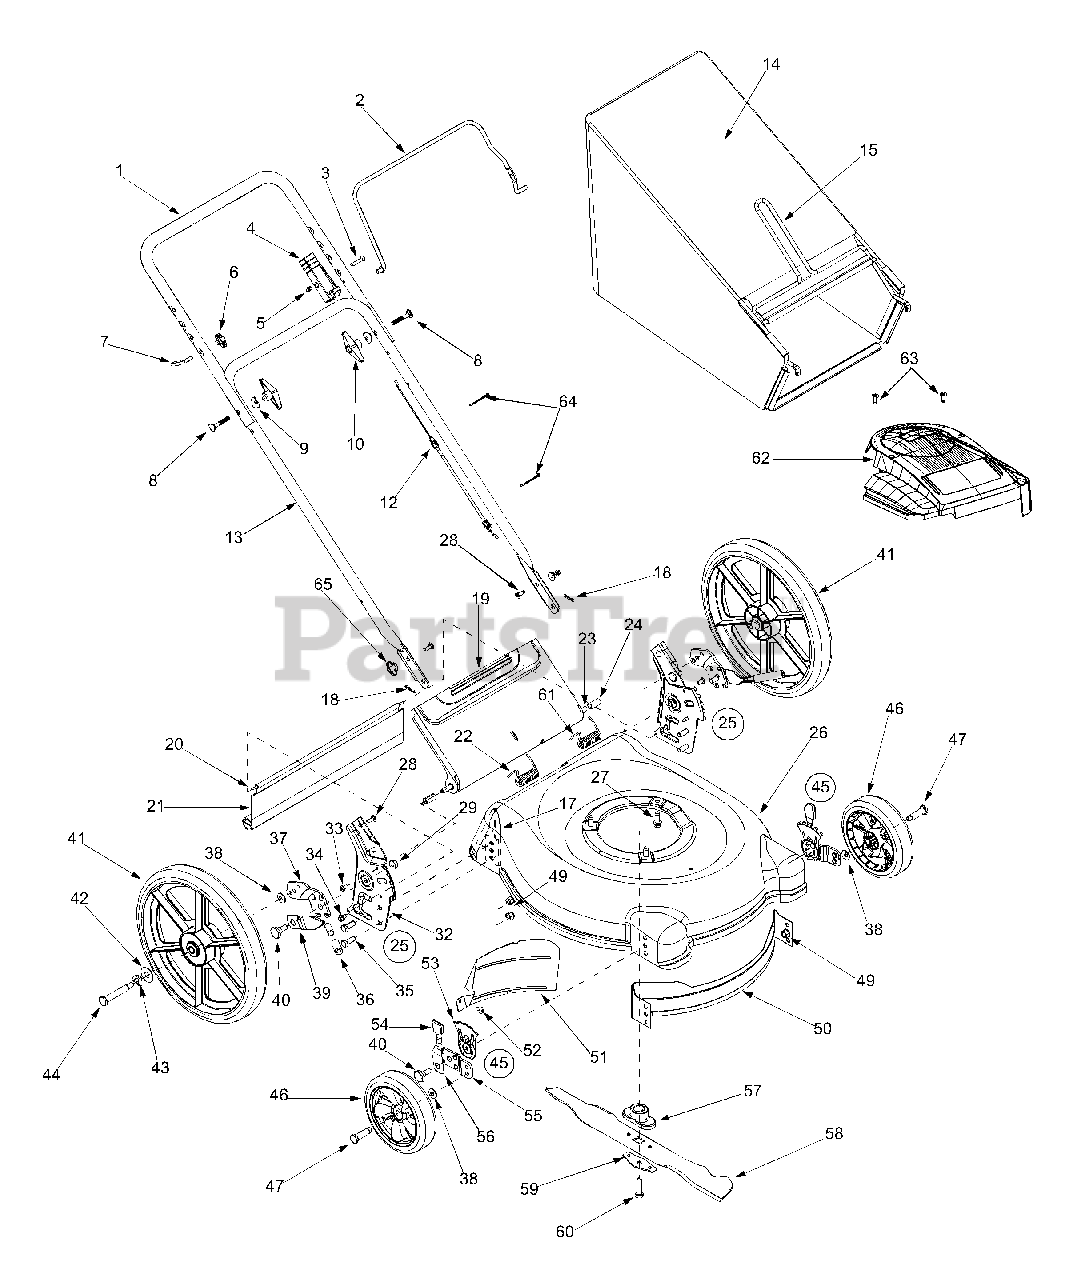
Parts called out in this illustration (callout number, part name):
3	C-Sunk Screw 1/4-20 x 1.3"
4	Throttle Housing
5	Hex Lock Nut 1/4-20
6	Handle Knob
7	Rope Guide
8	Carriage Bolt 5/16-18 x 2"
9	Shoulder Washer.320 ID x.930 OD
10	Wing Nut
12	Blade Control Cable
14	Grass Bag
18	Hairpin Clip
19	Grass Bag Door
20	Wire Rod
21	Trailshield
22	R.H. Door Spring
23	Chute Door Pivot Rod
24	Spacer .390 O.D. x .910 I.D. x .950"
25	Handle Bracket Assembly - LH
27	Hex Washer Screw 3/8-16 x 1.0
28	Hex Carriage Screw 1/4-20
29	Flange Lock Nut 3/8-16
32	Handle Bracket Assembly - RH
33	Machine Screw 1/4-20 x.500
34	Hex Washer Screw 1/4-14 x.625
35	Hex Cap Screw 3/8-16 x.75
36	Foam Grip
37	Pivot Bar - RH
38	Spring Washer.375 ID x.870 OD
39	Spring Lever
40	Shoulder Screw
41	Rear Wheel Assembly 14 x 1.8
42	Flat Washer.510 ID x 1.00 OD
43	Wave Washer.500 ID x 1.0 OD
44	Shoulder Screw
45	Front Height Adjuster - RH
46	Front Wheel Assembly 7 x 1.8
47	Shoulder Bolt
49	Flange Lock Nut 3/8-16
52	Tap Screw 1/4-14 x.625.
53	Height Adjustment Plate
54	Height Adjustment Knob
56	Spring Lever
57	Blade Adapter
58	21" Mulching Blade
59	Blade Bell Support
60	Hex Cap Screw 3/8-24 x 1.5
61	L.H. Door Spring
62	Engine Shroud
63	Screw
64	Cable Tie
65	Wing Nut
